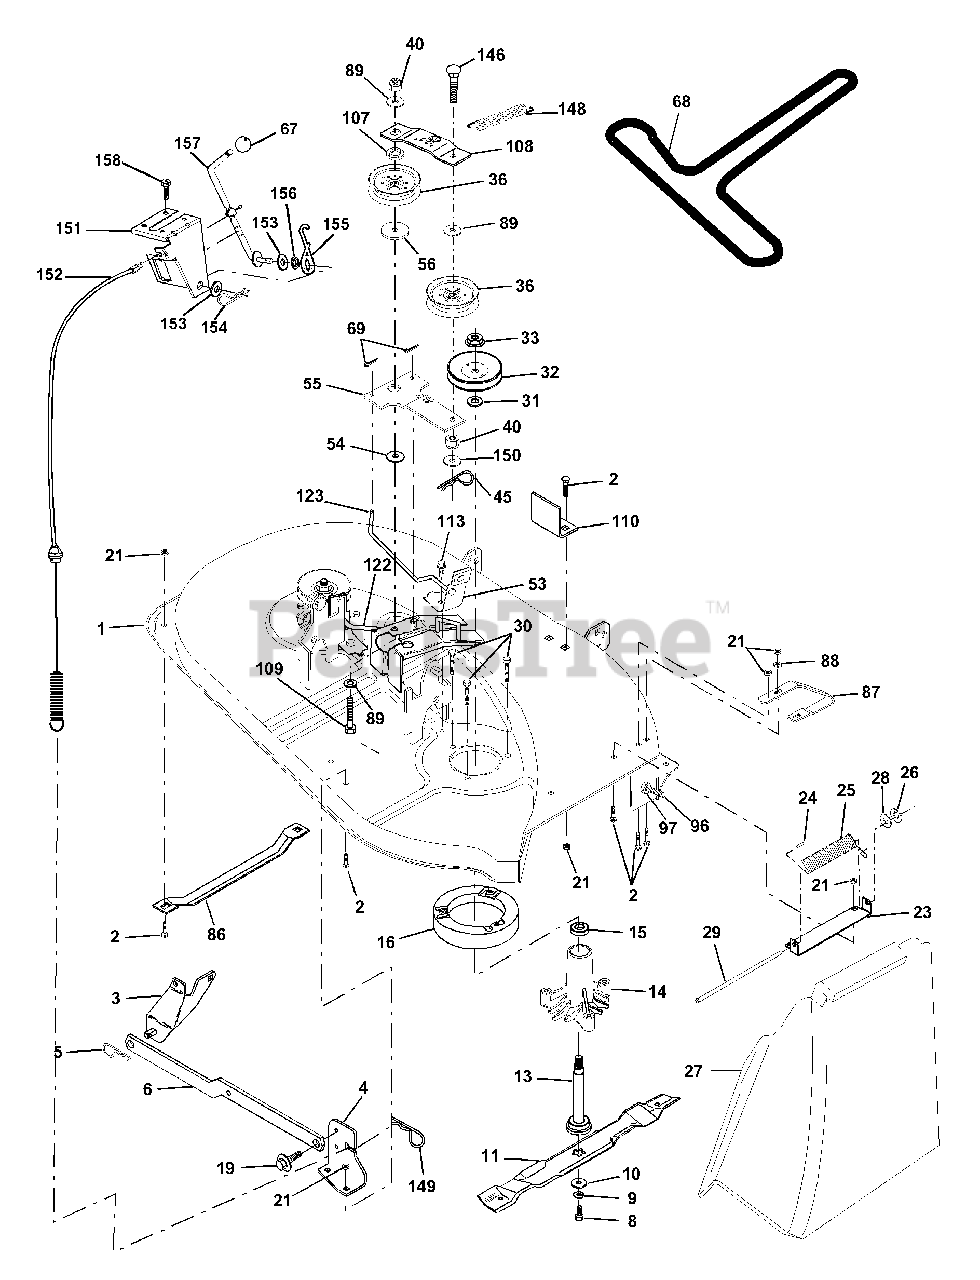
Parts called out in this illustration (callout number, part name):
1	Mower Deck Assembly
2	Bolt
3	Bracket Assembly,Sway Bar
4	Bracket Sway Bar Deck
5	Retainer Spring
6	Arm, Suspension, Rear
8	Bolt, Hex 3/8-24 x 1.25 Gr. 8
9	Washer, Lock Hvy Hlcl 3/8
10	Washer, Hardened
11	Blade, Mower 38
13	Shaft Assembly, Mandrel, Vented
14	Housing, Mandrel, Vented
15	Bearing, Ball, Mandrel
16	Stripper, Vented Mower Deck
19	Bolt, Shoulder
21	Nut Crownlock 5/16-18
23	Bracket, Mower Deflector
24	Cap, Sleeve
25	Spring, Torsion, Deflector
26	Nut, Push
27	Shield, Deflector
28	Washer 11/32 x 5/8 x 16 Ga.
29	Rod, Hinge
30	Screw Thdrol Washer Head
31	Washer, Spacer
32	Pulley, Mandrel
33	Nut, Toplock, Flanged
36	Pulley, Idler, Flat
40	Nut Crownlock 3/8-16
45	Retainer, Spring
53	Brake Assembly
54	Washer, Hardened
55	Idler Arm Assembly
56	Spacer, Retainer
67	Knob RD 3/8-16 Plstc Thd
68	Belt
69	Pin, Cotter 3/32 x 3/4
86	Runner, LH
87	Runner, RH
88	Washer 11/32 x 3/4 x 16 Ga
89	Washer 13/32 x 1 x 12 Ga
96	Bolt 3/8-16 x 1-1/4
97	Nut Centerlock 3/8-16
107	Spacer, Retainer
108	Stiffener, Idler Arm
109	Bolt, Hex Head 3/8-16 x 2-1/2
110	Upstop Deck Front 38
113	Screw 5/16-18 x 3/8
122	Rod, Brake, LH
123	Rod, Brake, RH
146	Bolt Carriage Idler
148	Spring Return Idler
149	Retainer Spring Yellow Zinc
150	Washer 9/32 x 3/4 x 16 Ga.
151	Bracket Clutch
152	Cable Clutch 38 In
153	Washer Flat 3/8" Type B
154	Spring Retainer
155	Spring Retention Lever
156	Spacer
157	Rod Clutch
158	Screw Hex Thd Cut 1/4-20x5/8
